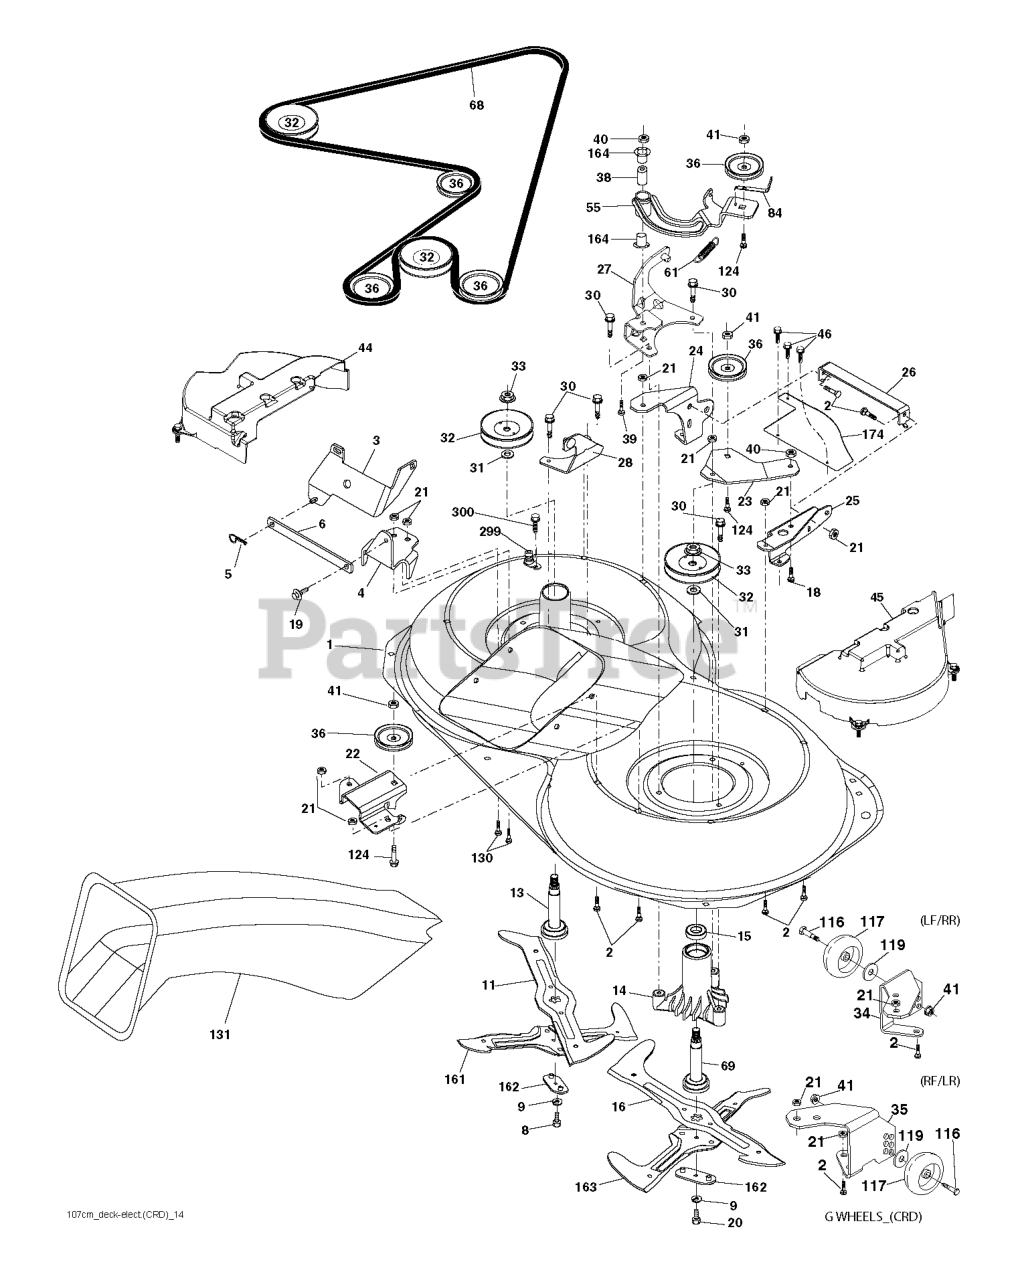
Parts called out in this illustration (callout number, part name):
1	Housing Asm. Mower 107 CRD
2	RP BOLT 5/16-18 X3/4 ZN/YEL GR
3	BRACKET.ASM.BAR.SWAY.CHASS
5	RETAINER-SPRNG RB
6	BAR.SWAY.92.CRD
8	BOLT.3/8-24X1.25 GR8
9	LOCKWASHER
11	BLADE.3N1.LH.CRD
13	SHAFT ASM VENT
14	HOUSING.MANDREL.VENTED (MACHD)
16	BLADE.3N1.RH.CRD
19	BOLT SHD 5/16-18
20	BOLT.3/8-24X1.25GR8. LHTHRD
21	LOCKNUT
22	BRACKET.IDLER.RR.107.CRD
24	BRACKET
25	BRACKET RF
26	SUPPORT
28	BRACKET
30	SCREW, WASHER HEAD
31	WASHER.SPACER.MANDREL
32	PULLEY.MANDREL.4.80 PD.2006
33	NUT.FLANGE.LOCK.TOP
34	BRACKET
35	BRACKET
36	PULLEY.IDLER.4.25
41	NUT LOCK FLG 3/8-16 UNC
44	COVER MANDREL LEFT
45	COVER MANDREL RIGHT
46	SCREW.1/4-20X5/8
55	ARM.IDLER.107.CRD
61	SPRING
68	HEX-BELT 107 MOWER
69	SHAFT.ASM.W/LWR.BRG.RH.THREAD
84	KEEPER, BELT IDLER
116	BOLT.SHOULDER.3/8-16X3-5/8.
117	RP WHEEL. GUAGE RALLY
119	WASHER
124	BOLT.3/8-16X1.50
130	BOLT.CARR.SQNK.5/16-18UNC.X3/4
131	CHUTE BAGGER
163	BLADE.CROSS.RH.CRD.107
164	BRNG T
174	PLATE
299	PORT.WASHOUT
300	SCREW.TT.#10-32X.5.3/8.FLANGE
